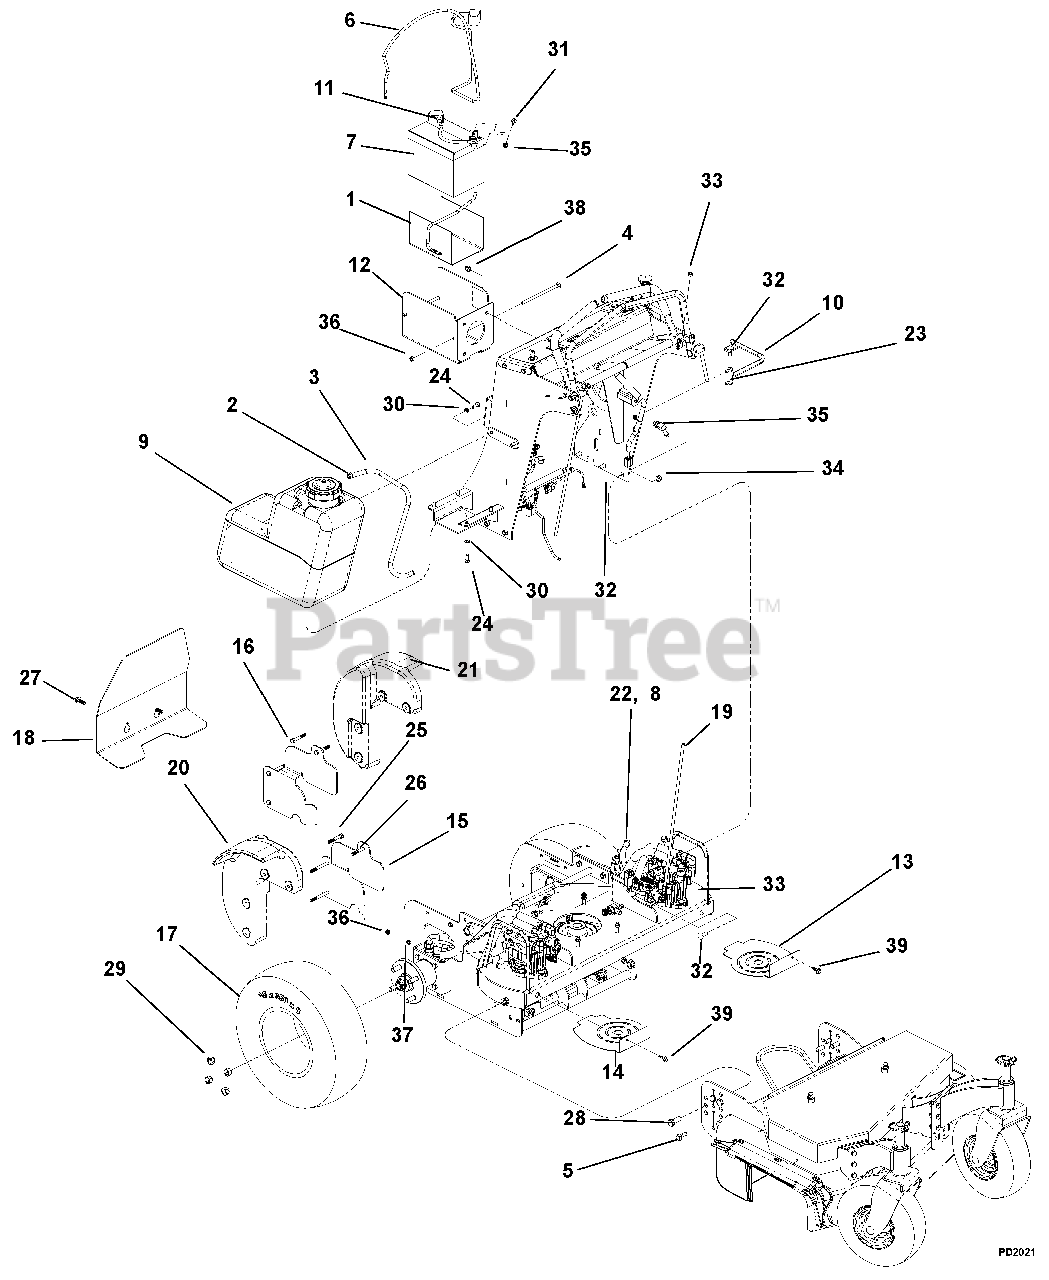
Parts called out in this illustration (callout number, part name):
1	STRIP, RUBBER
2	CLAMP
3	HOSE, 1/4" ID LOW PERM FUEL 50
4	BOLT, 5/16X6 LONG NK RD HD D-Z
5	BOLT, 1/2X1.06X3/8-16 SLD 5 Y
6	CABLE, BATTERY STARTER 48"
7	BATTERY, 12V-U1-CCA270MIN
8	PIN, CVS SPG 3/8" YOKE SPEC Y
9	TANK-FUEL 34P/S W/CAP W/O LOGO
10	WLDMT, RESERVOIR GUARD
11	CABLE, BATTERY GROUND, 25"
12	CONSOLE BATTERY BRACKET
13	SHIELD, LH PUMP
14	SHIELD, RH PUMP
15	SHIELD, RH MOTOR
16	SHIELD, LH MOTOR
17	ASSY, TIRE/WHL 18-6.50-8
18	SHIELD, ENGINE
19	ROD, CONTROL 5/16-24 X 22.75
20	RH CAST WEIGHT MACHINED
21	LH CAST WEIGHT MACHINED
22	YOKE, 3/8-24 RH ADJUSTABLE
23	BOLT, 1/4-20X.750 HEX 5 Y
24	BOLT, 5/16-18X.750 HEX 5 Y
25	BOLT, 5/16-18X2.00 HEX 5 Y
26	BOLT, 5/16-18X3.00 HEX 5 Y
27	BOLT, 3/8-16X1.00 FGH 8 Y
28	BOLT, 1/2-13X1.25 HEX 5 Y
29	NUT, 1/2-20 LUG C
30	ARM, IDLER PIVOT
31	PLATE, ENGINE MOUNT
32	BOLT, 3/8-16X1.00 CRG 5 SN Y
33	NUT, 5/16-24 STD HEX GR5 Y
34	LOCKNUT, 3/8-16 WHIZ Y
35	LOCKNUT, 1/4-20 WHIZ Y
36	LOCKNUT, 5/16-18 NYLOC Y
37	LOCKNUT, 1/2-13 WHIZ GR5 Y
38	LOCKNUT, 3/8-16 NYLOC Y
39	@SCR-TAP .38-16X.50 HWH TR YWZ
